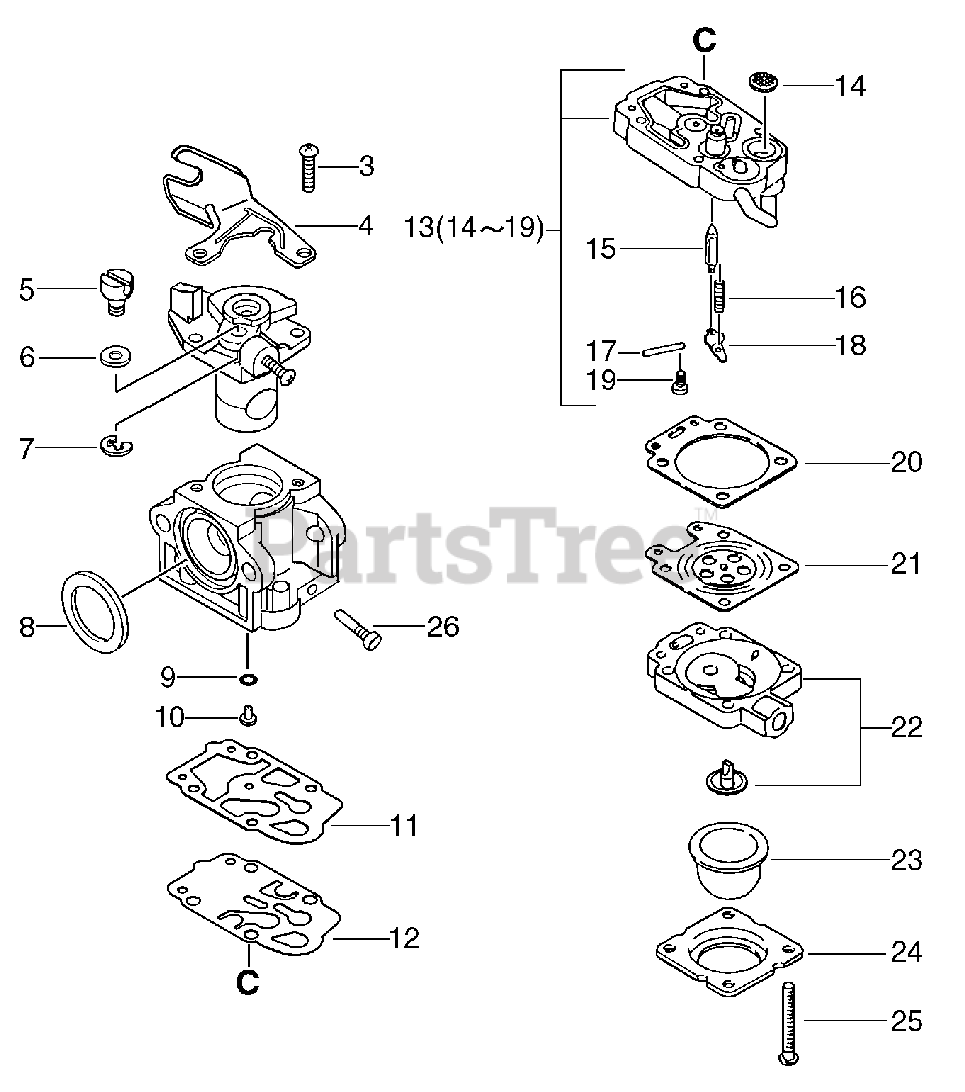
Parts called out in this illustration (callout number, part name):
4	BRACKET, THROTTLE CABLE
8	RING, PACKING
9	O-RING
10	JET, MAIN
11	GASKET, PUMP
12	DIAPHRAGM, FUEL PUMP
13	BODY ASSY, PUMP
14	SCREEN, FUEL INLET
15	VALVE, INLET NEEDLE
16	SPRING, METERING LEVER
17	PIN, METERING LEVER
18	LEVER, METERING
20	GASKET, METERING DIAPHRAGM
21	DIAPHRAGM, METERING
22	BODY ASSY, PURGE
23	BULB, PURGE
24	RETAINER, PURGE BULB
26	NEEDLE, HIGH SPEED
